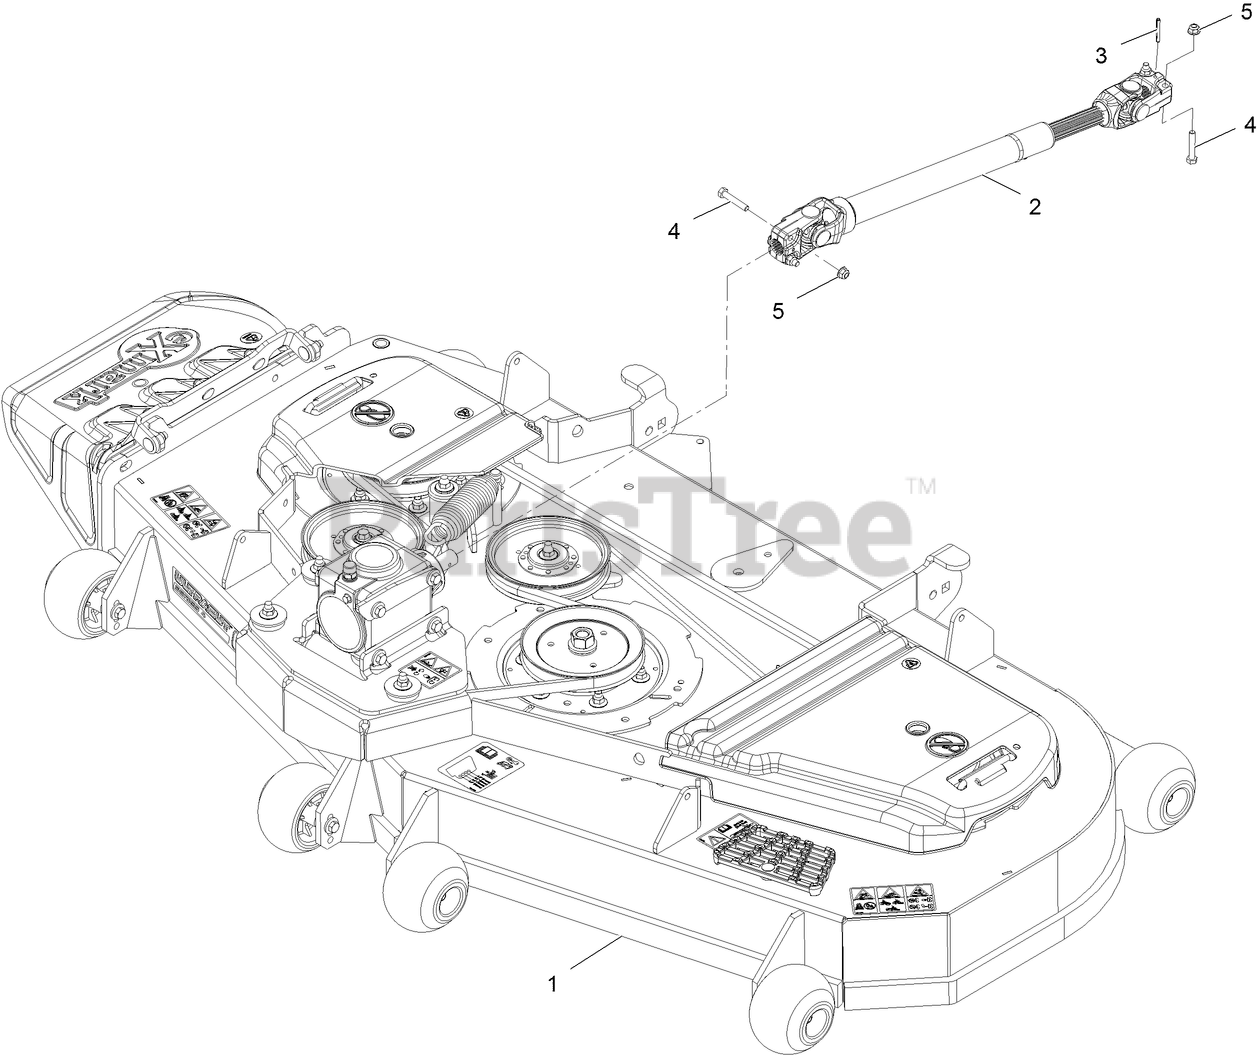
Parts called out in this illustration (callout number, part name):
1	Deck ASM-604
2	DRIVESHAFT ASM
3	PIN-ROLL
4	SCREW-HH
5	NUT-HF, NI
